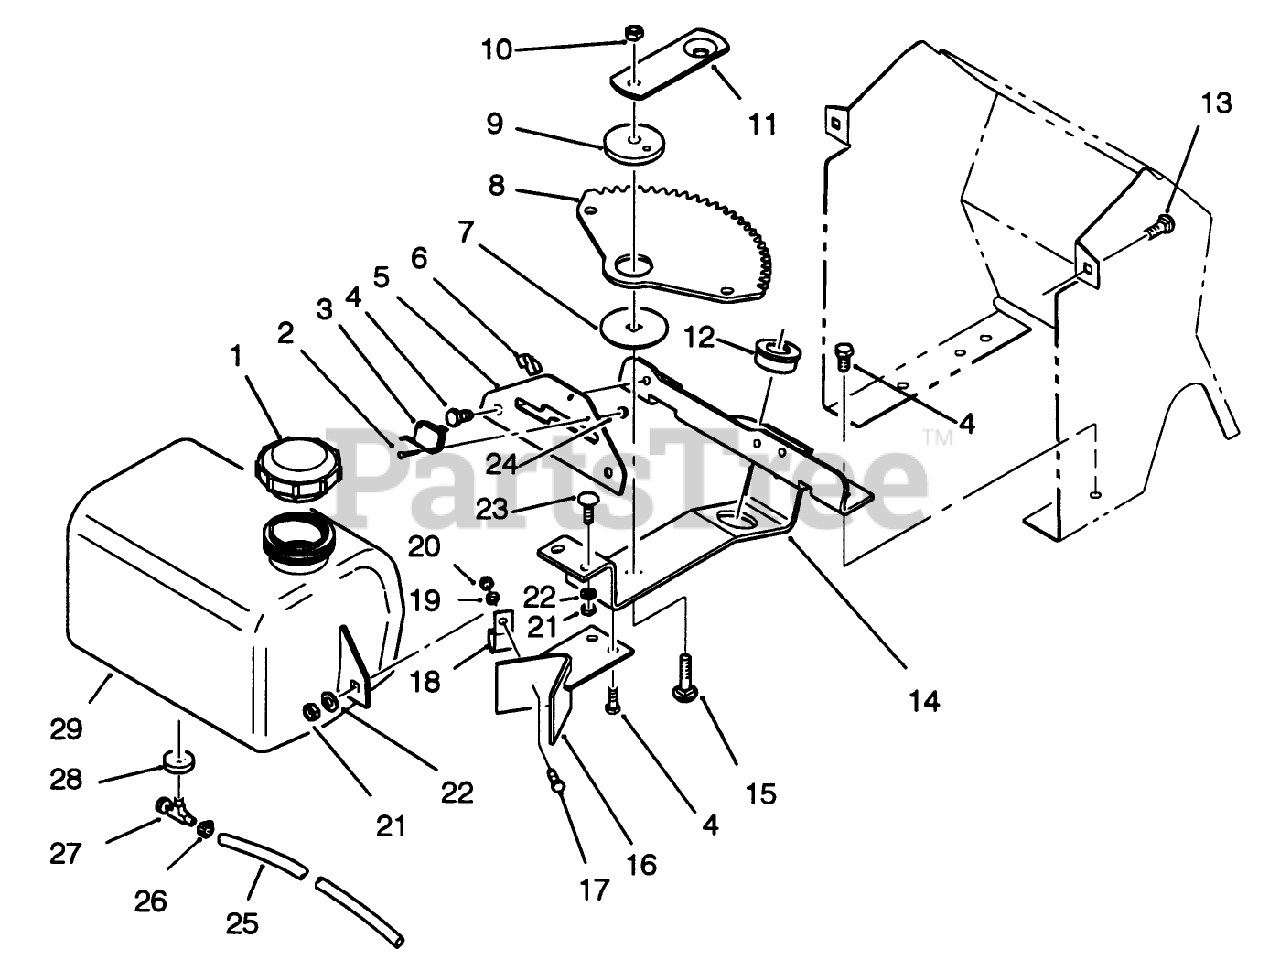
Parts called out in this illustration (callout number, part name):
1	CAP GAS
3	SWITCH - CLUTCH
6	CLIP-CABLE
7	WASHER-BEARING
9	BUSHING
12	BEARING-WHEEL
13	SCREW-CARR
15	SCREW-CARR
18	CLIP
20	NUT-LOCK, NI
21	NUT-LOCK, NI
22	WASHER-PLAIN
26	CLAMP-HOSE
27	VALVE-FUEL
